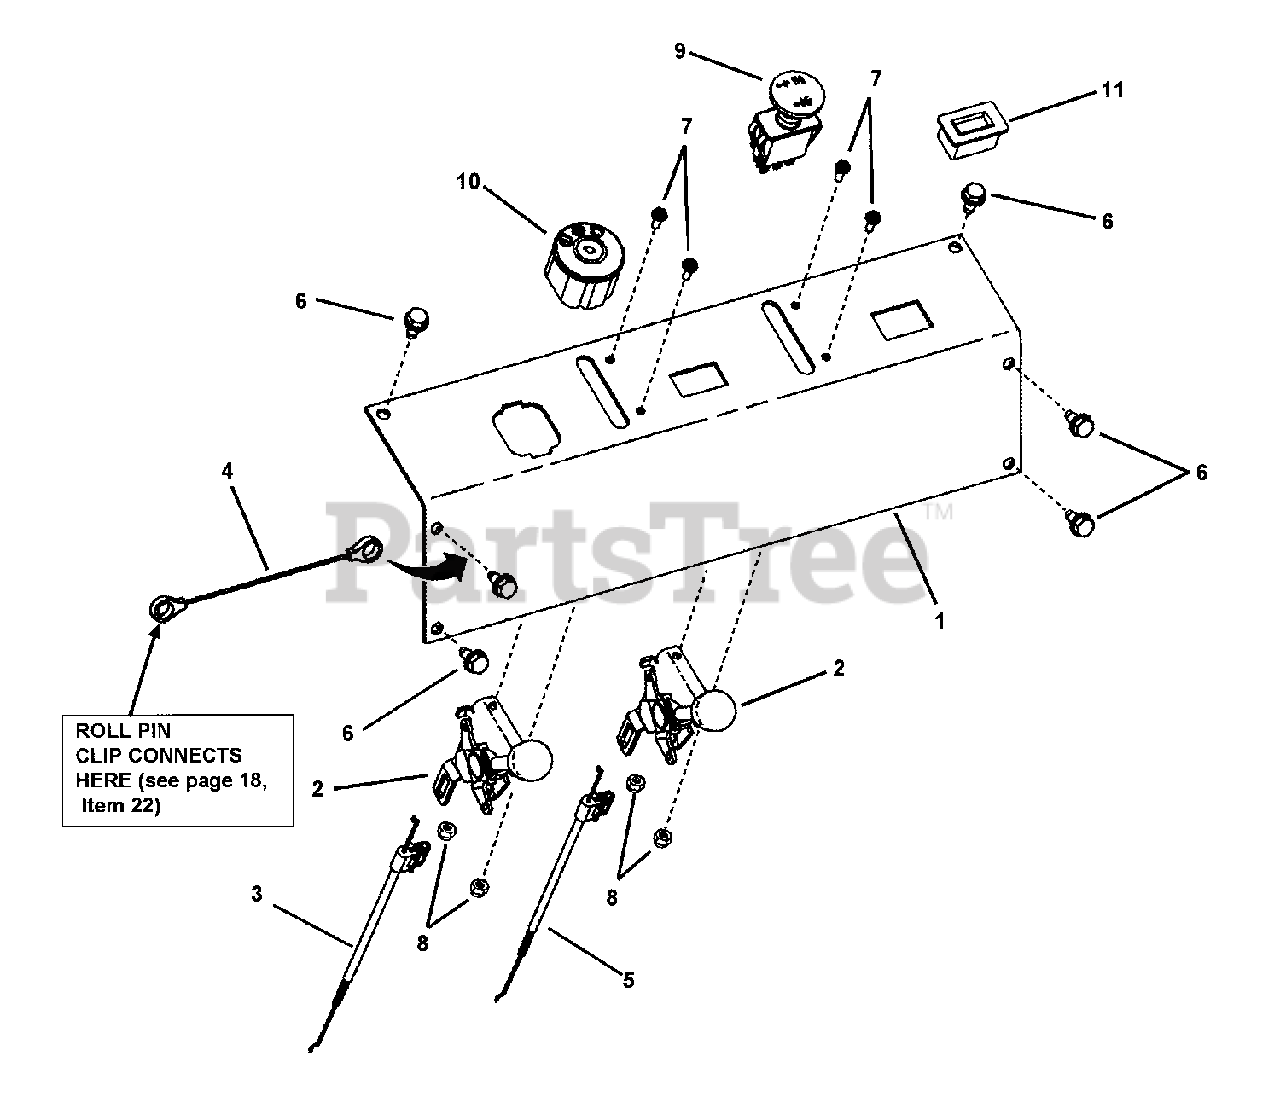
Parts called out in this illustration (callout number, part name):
1	CONTROL PANEL
2	CONTROL LEVER, Throttle/Choke
3	CONTROL CABLE, Throttle
4	STRAP, Tether
5	CONTROL CABLE, Choke
6	SCREW, 5/16-18 x 5/8" Hex Washer Self-Tap
7	SCREW, #10-32 x 5/8" Hex Washer Self-Tap
8	NUT, #10-32 Nyloc
9	SWITCH, PTO, Yellow
10	SWITCH, Ignition
11	HOUR METER w/Flash Alerts
